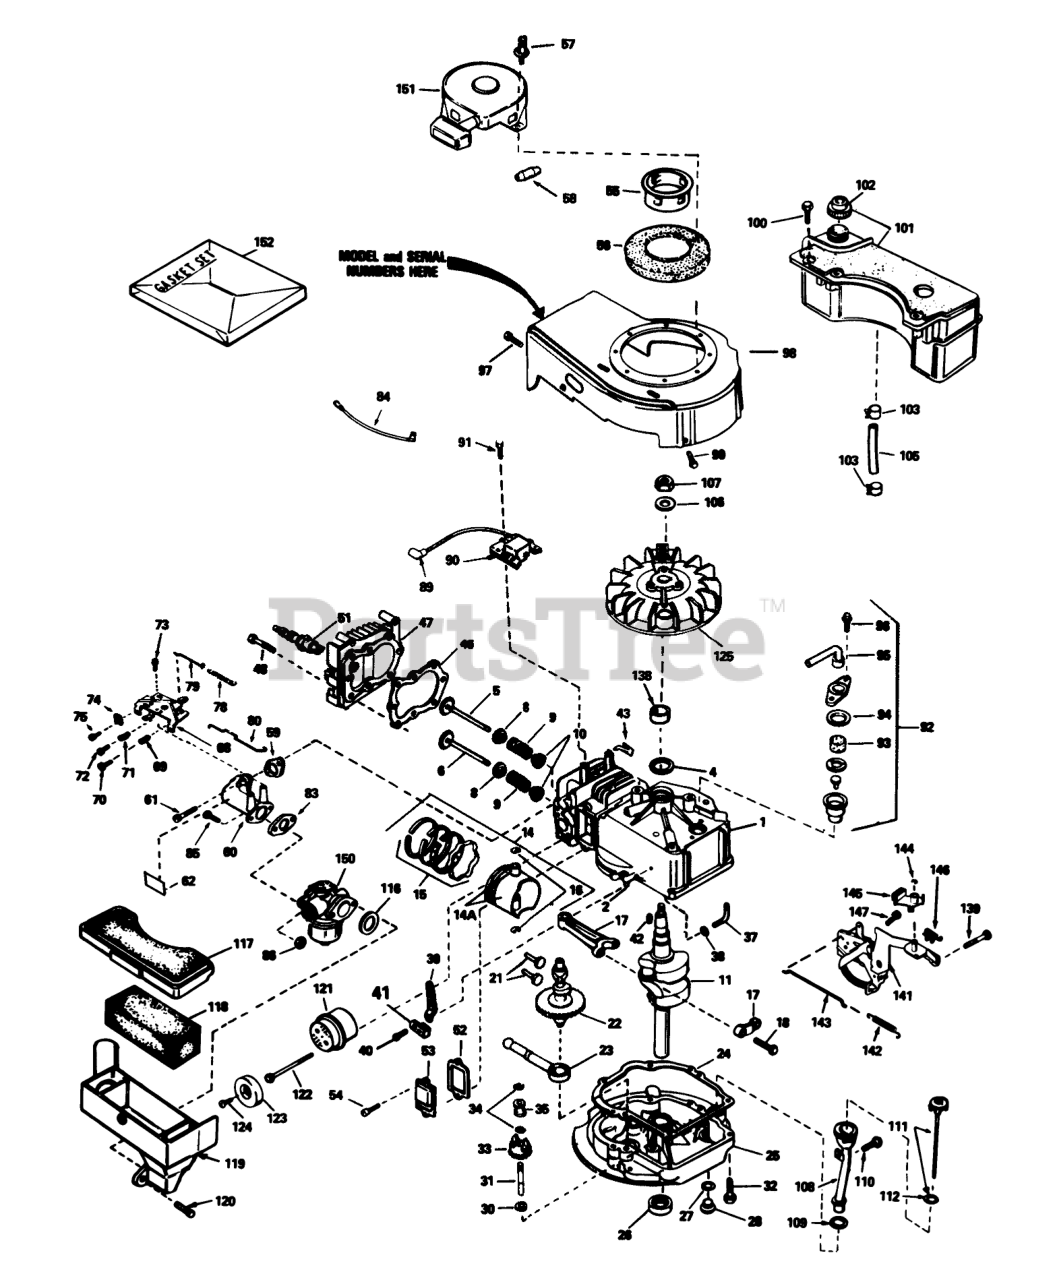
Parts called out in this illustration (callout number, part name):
1	Cylinder Assy. (Incl. #2 & 4)
2	Pin-Dowel
4	Seal-Oil
5	Valve-Intake (Std.)(Incl. #10)
5	Valve-Intake (1/32" Oversize)(Incl. #10)
6	Valve-Exhaust (Std.)(Incl. #10)
6	Valve-Exhaust (1/32" Oversize)(Incl. #10)
8	Cap-Upper Valve Spring
9	Spring-Valve
10	Cap-Valve, Spring
11	Crankshaft
14	Piston-Pin & Ring Assy. (Std.)(Incl. #14A, 15 & 16)
14	Piston-Pin & Ring Assy. (.010 Oversize)(Incl. #14A, 15 & 16)
14	Piston-Pin & Ring Assy. (.020 Oversize)(Incl. #14A, 15 & 16)
14A	Piston & Pin Assy. (Std.)(Incl. #16)
14A	Piston & Pin Assy. (.010 Oversize)(Incl. #16)
14A	Piston & Pin Assy. (.020 Oversize)(Incl. #16)
15	Piston Ring Set Std.
15	Piston Ring Set .010 O.S.
15	Piston Ring Set .020 O.S.
16	Ring-Retaining, Piston Pin
17	Rod Assy.-Connecting (Incl. #18)
18	OA Bolt-Connecting Rod
21	Lifter-Valve
22	Camshaft(Mech.Comp. Release)
23	Oil Pump ASM
24	Gasket, Mounting
25	Flange Assy.-Mounting (Incl. #26, 27, 28 & 31)
26	Seal Oil
27	Gasket-Oil Drain
28	Plug Oil Drain
30	Washer-Flat
31	Shaft-Governor
32	Screw (1/4-20 x 1-1/4)
33	Gear Assy.-Governor (Incl. #30)
34	Ring-Retaining
35	Spool-Governor
37	Rod-Governor (Incl. #38)
38	Washer-Flat
39	Governor Lever
40	Screw
41	Clamp-Lever, Governor
42	Key-Flywheel
43	Clip-Wire
46	Gasket-Cylinder Head
47	2025A67 ADD.ASSEMBL
48	Screw (5/16-18x1-1/2)
51	Plug, Spark (Autolite 458, Champion J-19LM or equiv.)
52	Gasket-Breather
53	Cover-Valve
55	Cup-Starter
56	Screen-Starter
57	Pop Rivet (Can be purchased locally)
58	Retainer-Starter Rope
59	Gasket-Intake
60	Pipe-Intake (Incl. #59)
61	Screw (1/4-20 x 1)
62	Decal-Primer
68	Control Assy.-Remote Speed (Incl. #69-72)
69	61709/GIL1515A/95-5
70	Screw
71	Spring-Compression
72	Screw
73	Screw (10-24 x 9/16)
74	Conduit
75	Screw (10-32 x 3/8)
78	Spring Governor
79	2035A67 ADD.ASSEMBL
80	Link-Throttle
83	Gasket
84	Ground Wire
85	Screw (1/4-28 x 7/8)
86	Nut and Lock Washer (1/4-28)
89	Cover-Spark Plug
90	Lamination & Coil Assy. (Solid State)(Incl. #89)
91	Screw
92	Breather Assy. (Incl. #93-96)
93	Element-Breather
94	Gasket-Breather
95	Tube, Breaker
96	Screw (10-24 x 9/16)
97	Screw (10-24 x 9/16)
98	Housing-Blower
99	Screw (1/4-20 x 1/2)
100	Screw (10-32 x 35/64)
101	Tank Assy.-Fuel (Incl. #102)
102	Cap-Fuel
103	Clamp-Line, Fuel
105	Line-Fuel
106	Washer-Belleville
107	Nut-Flywheel
108	Tube-Oil Fill
110	Screw (10-32 x 1/2)
111	Dipstick-Oil (Incl. #112)
116	Gasket-Cleaner, Air
117	Cover Air Cleaner
118	Filter-Air Cleaner
119	Body Air cleaner
121	Muffler (Incl. #122)
123	Cover-Muffler
124	Screw
125	Flywheel
139	Screw (1/4-20 x 3/8)
141	Bracket Assy.
142	Spring-Extension
143	Link-Control
144	Ring-Retaining
145	Lever-Brake
146	Terminal
147	Screw-Hex. Hd.
150	Carburetor (Incl. #83)
151	tarter-Rewind
152	Gasket Set
